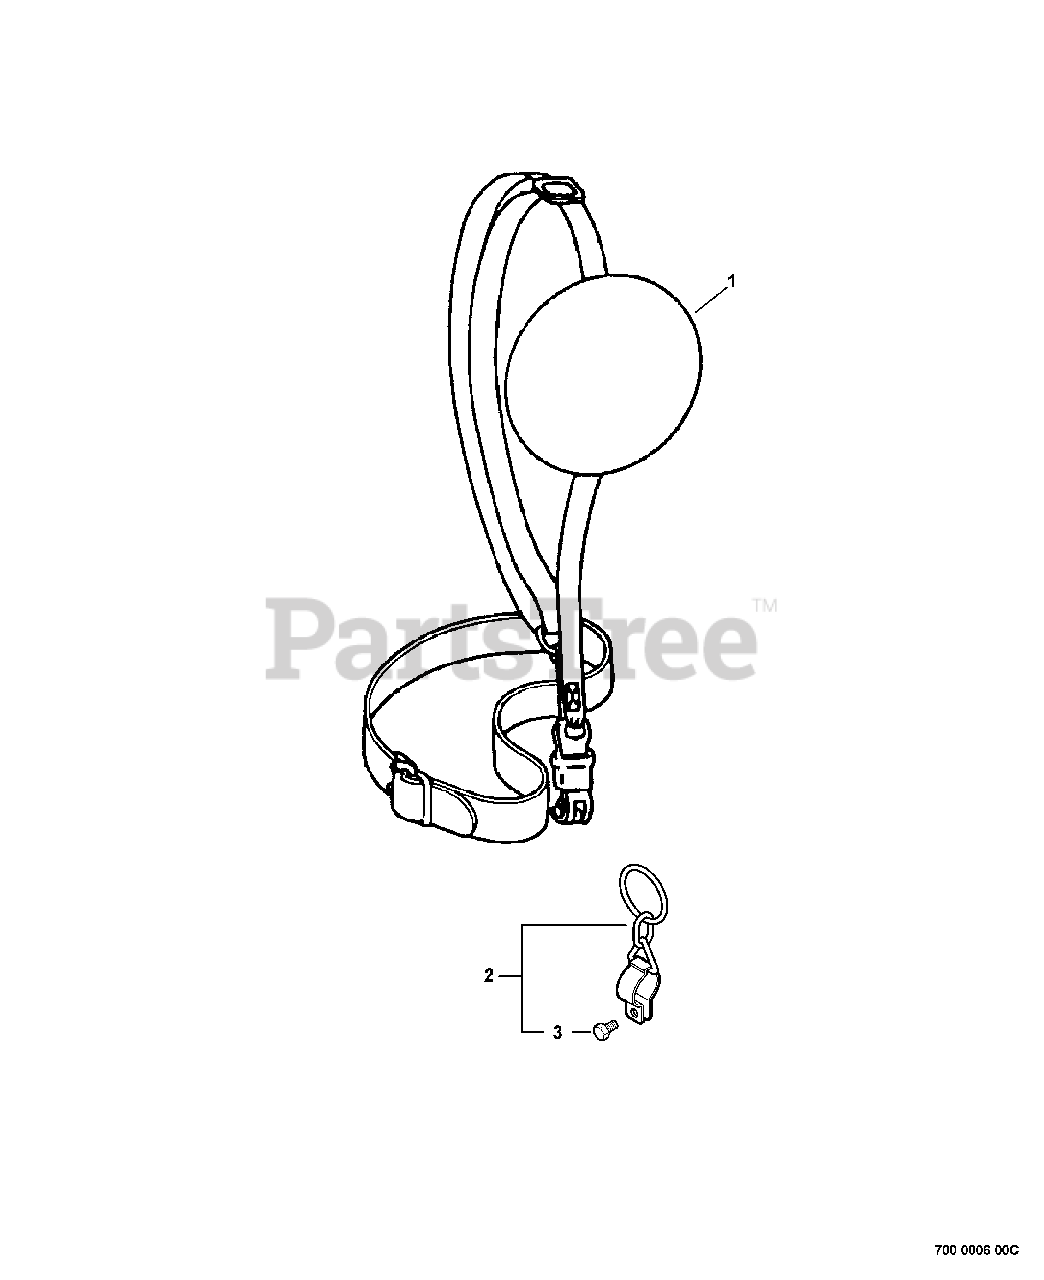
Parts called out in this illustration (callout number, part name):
1	HARNESS ASSY
2	HANGER KIT
3	BOLT - 5X12
